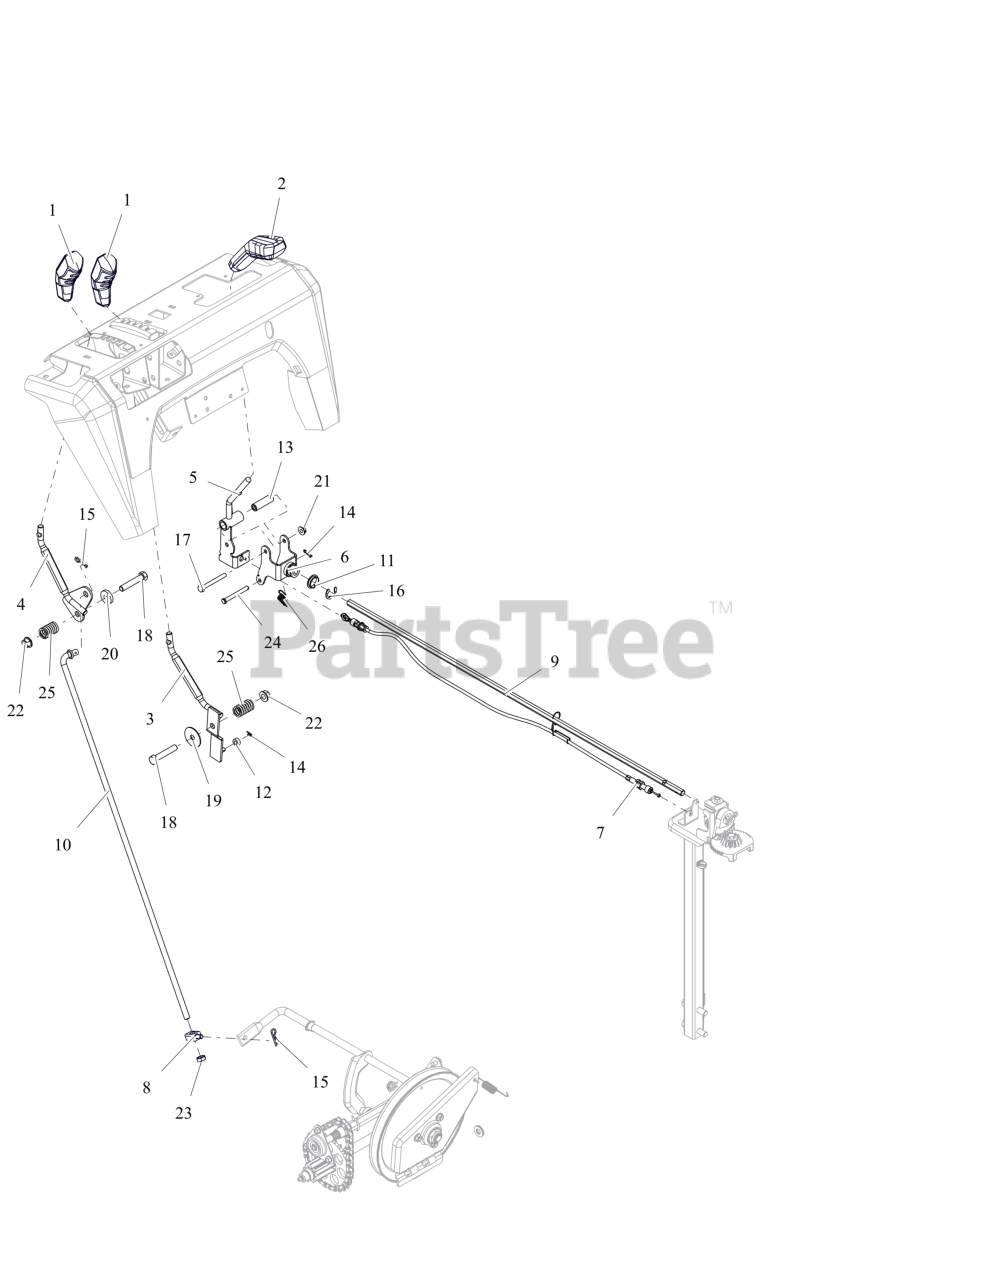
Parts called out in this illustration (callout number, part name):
1	KNOB, CONTROL
2	HANDLE, QUICK TURN
3	WELDMENT,LG DASH DEFL CONTROL
4	WELDMENT,LG DASH SPEED CONTROL
5	WELDMENT, CONTROL LEVER
6	WELDMENT, CONTROL BRACKET
7	CABLE, CHUTE LOCK, PRO
8	PIVOT,SHIFT ROD .375-16(TRUNN)
9	ROD, HEX - CHUTE ROTATION
10	ROD, SHIFT - PRO
11	BUSHING, POLYLINER-.75 SNAPIN
12	BSHG-SLV .265X.500X.219
13	BSHG, SLV .265X.505X1.665
14	PIN, HAIR #178 .06X.77 ZCC
15	PIN, HAIR #213 .08X1.19 ZCC
16	E-RING .750X.050
17	BLT,HEX .25-20X2.25 G5 ZCC
18	BLT,HEX .38-16X2.00 G5 ZCC
19	WSHR,FLT .380X1.50X.062 ZCC
20	WSHR, FLT .406X1.00X.188 ZCC
21	NUT-LK-CTR-FLG .25-20 ZC120
22	NUT-LK-TOP-FLG .38-16 ZC120
23	NUT-JAM .375-16 G2 ZCC
24	PIN, CLEVIS - .25 X 2.25 ZCC
25	SG-COMP .125X.781X1.250
26	SPRING-EXT .047X.438X1.45
